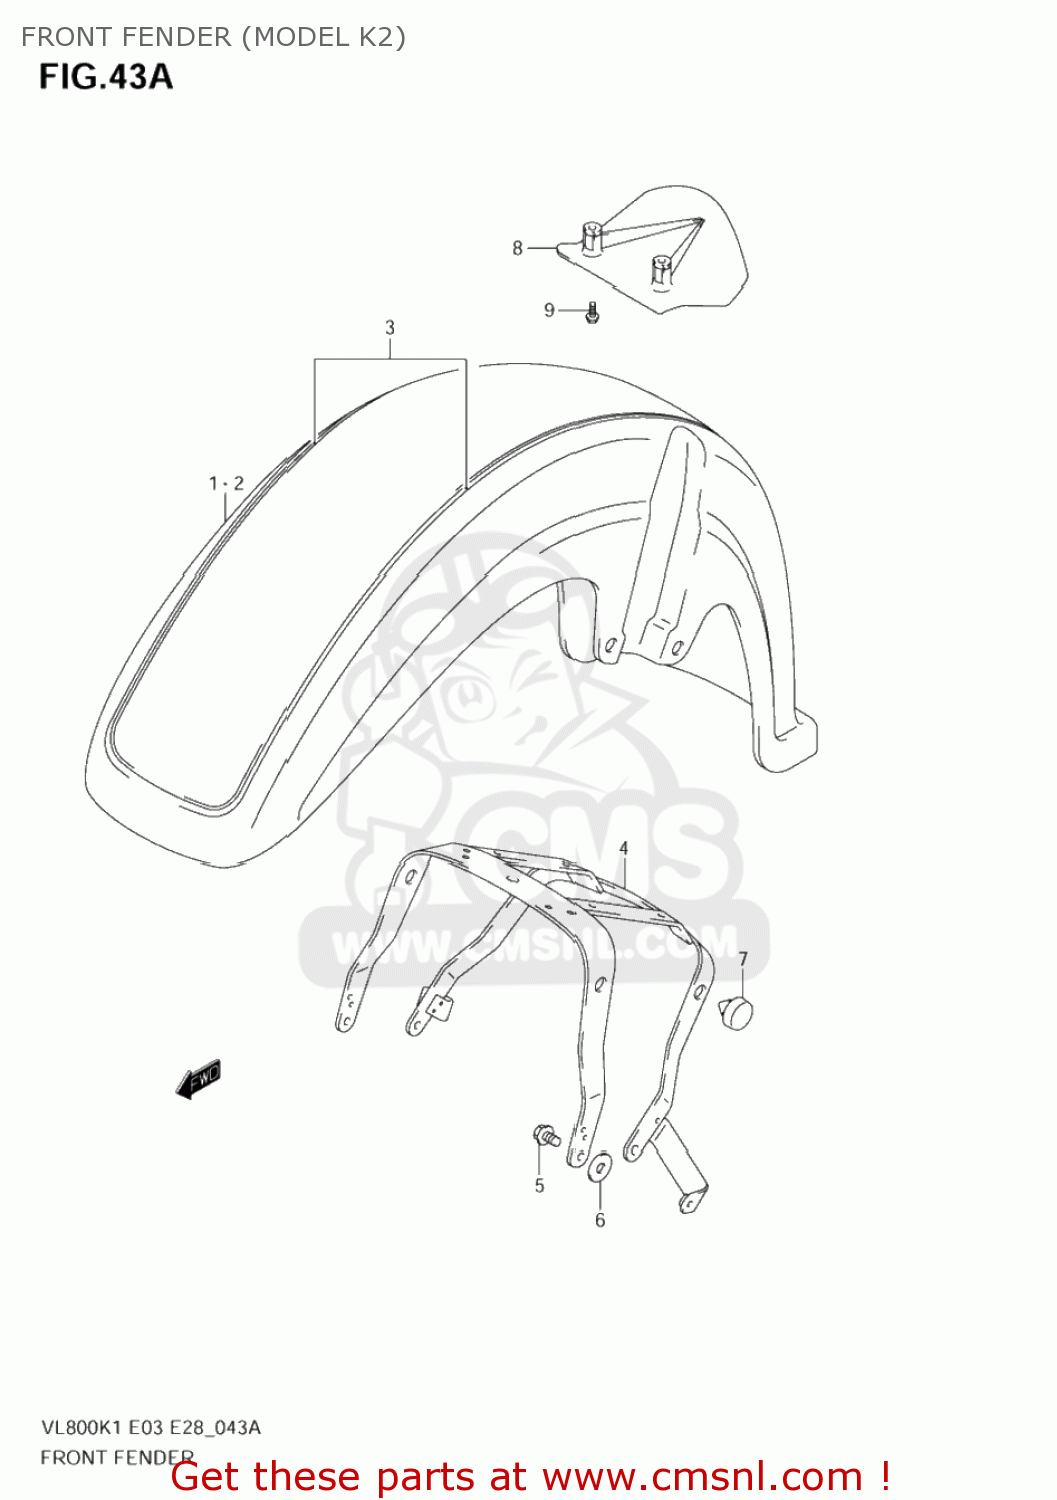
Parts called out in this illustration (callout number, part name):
1	FENDER,FR
2	FENDER,FR
3	TAPE SET,FR FENDER
4	BRACE,FR FENDER
5	BOLT
6	WASHER,FR FENDER
7	CUSHION
8	WING,FR
9	BOLT(6X16)
